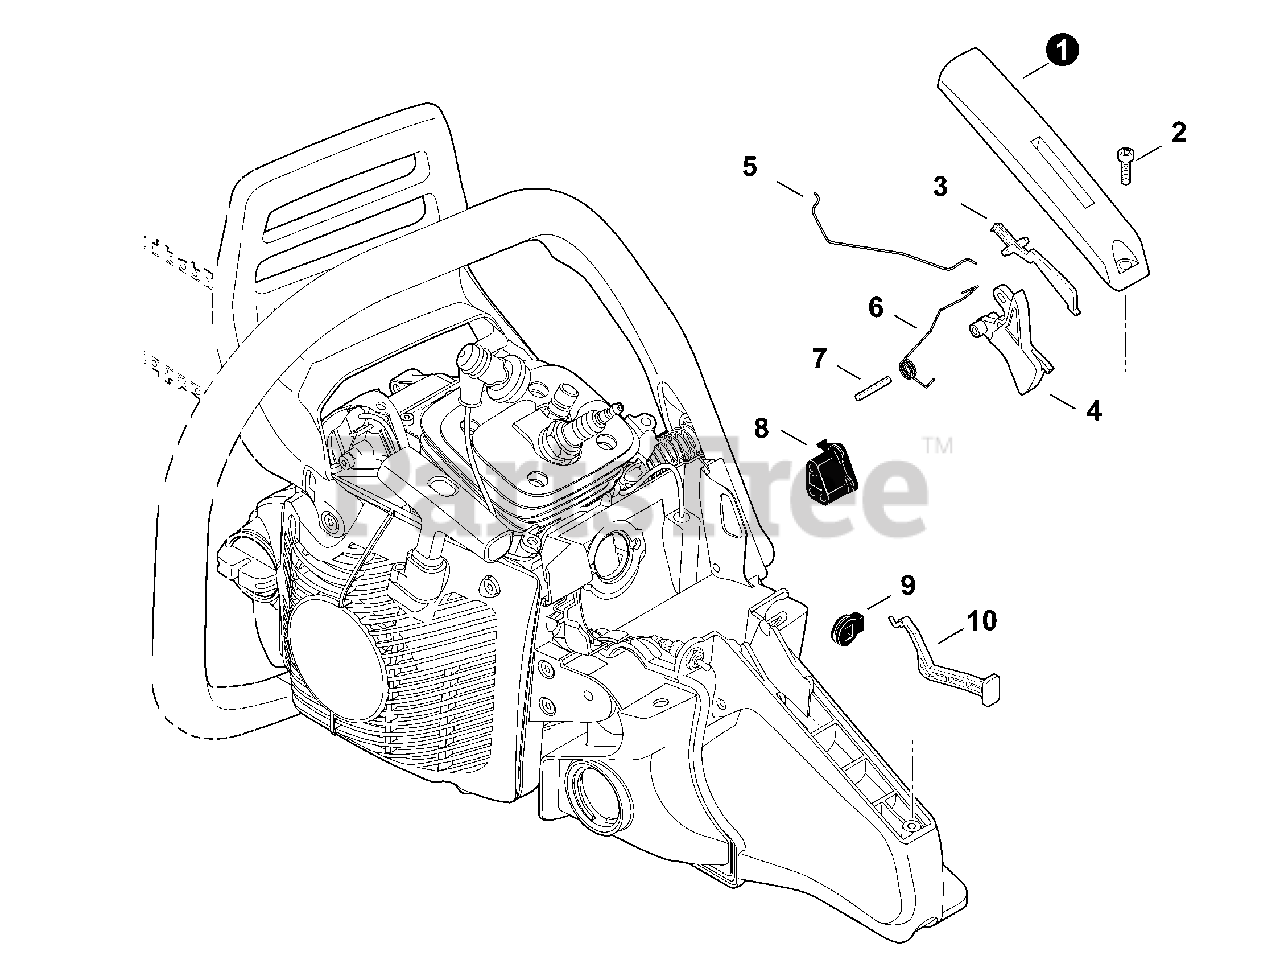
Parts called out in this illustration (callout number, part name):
1	COVER, HANDLE
2	BOLT, TORX 4×12
3	LEVER, THROTTLE LOCKOUT
4	TRIGGER, THROTTLE
5	ROD, THROTTLE
6	SPRING, TORSION
7	PIN, SPRING 4×25 SUS
8	GROMMET, NEEDLE
9	GROMMET, CHOKE
10	ROD, CHOKE
